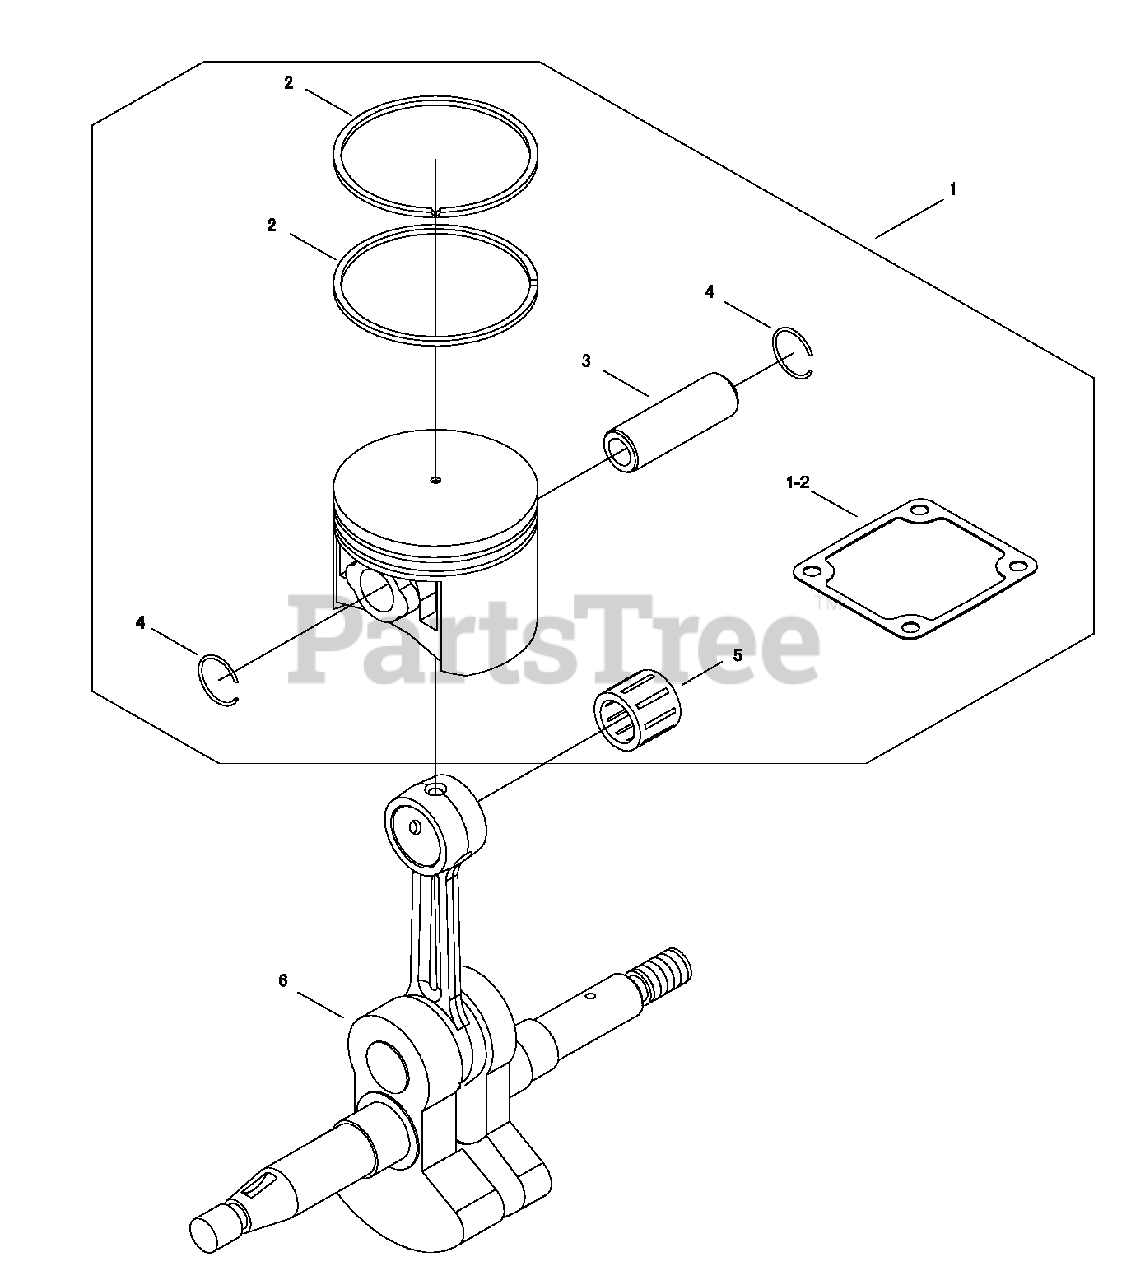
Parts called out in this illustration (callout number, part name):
1	PISTON KIT
2	RING, PISTON
3	PIN, PISTON 10
4	RING, SNAP
5	BEARING, NEEDLE
6	CRANKSHAFT ASSY
